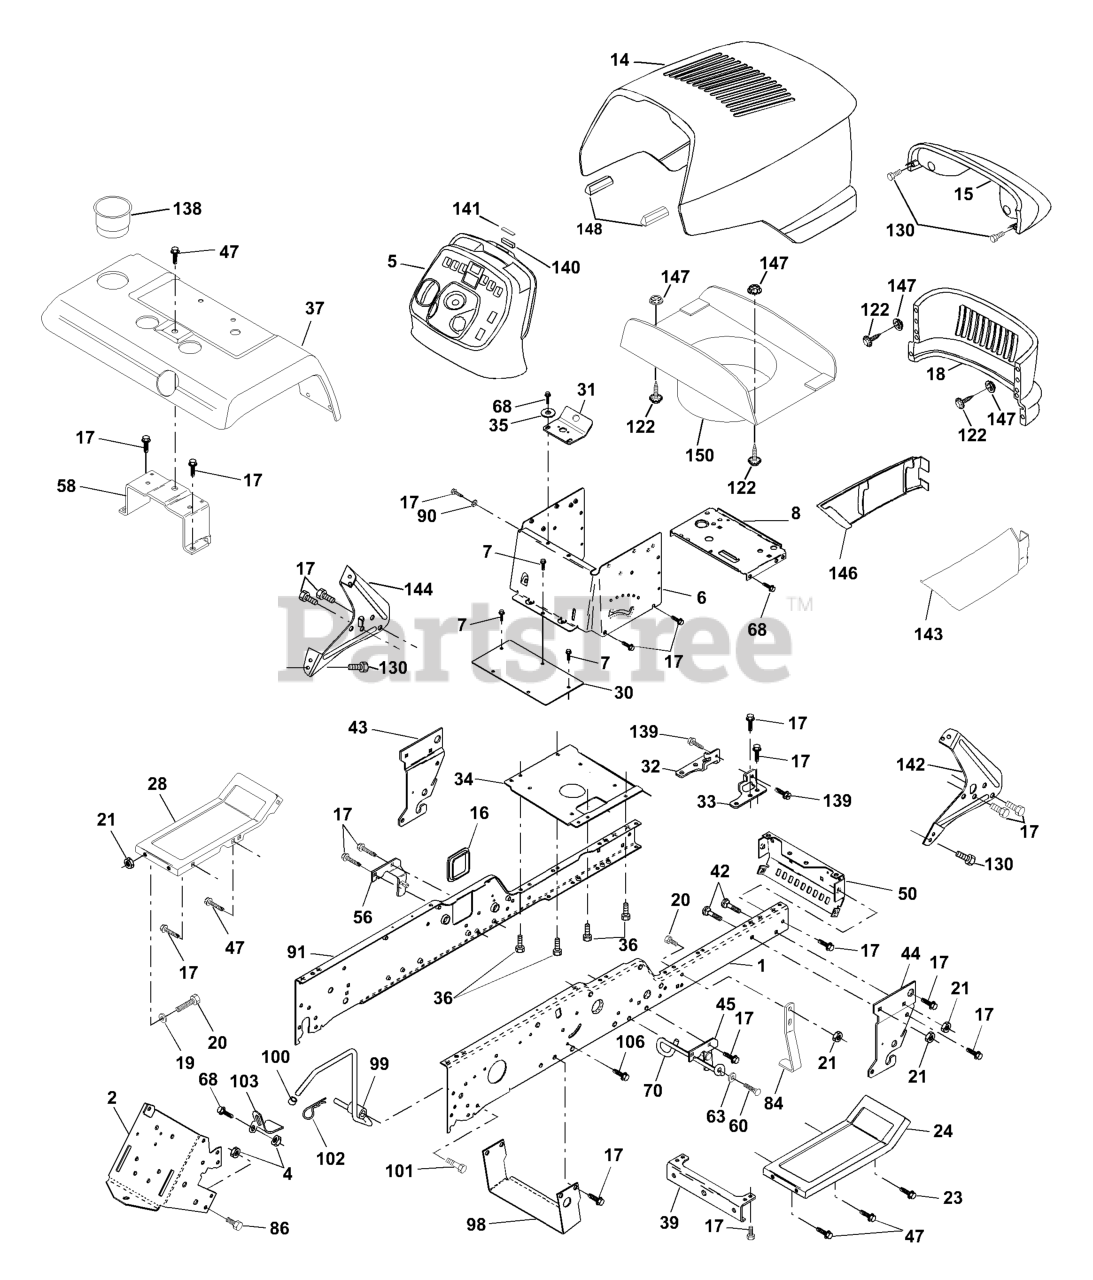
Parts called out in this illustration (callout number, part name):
1	RAIL, FRAME RH
2	DRAWBAR, GT
4	Nut, Lock Hex 7/16 Unc
5	DASH.STEALTH.YTGT.2CYL.BLK
6	DASH VGT, LOWER
7	SCREW
8	SUPPORT, BATTERY
14	HOOD ASM.
15	LENS, HEADLIGHT BAR
16	COVER ACCESS
17	SCREW 3/8-16X3/4
18	GRILLE
19	WASHER
20	BOLT
23	SCREW THDROL 3/8-16 X 1-1/2
24	FOOTREST RH
28	FOOT REST LH
30	SADDLE.HYDRO.95
31	BRACKET SUPT 1-PC VGT STEERING
34	PLATE ASM ENG CHASSIS
35	WASHER
36	SCREW 5/16"
37	FENDER
39	BRACKET AXLE, FRONT
42	BOLT D
43	FRONT SUSPENSION BRKT LH
44	FRONT SUSPENSION BRKT RH
45	BRACKET SUSP RH
47	SCREW 3/8-16X1/2
50	BRACKET, CHASSIS FRONT
56	BRACKET ASM, SUSP CHASSIS
58	BRACKET ASM, FENDER
60	SCREW.3/8-16
63	WASHER
68	Screw, 5/16-18 x 1/2
70	BELT GUIDE
84	MOWER STOP
86	BOLT
90	LOCKWASHER
91	RAIL, FRAME LH
98	BRACKET CHASSIS
99	ROD ASMBLY BYPASS
100	PLUNGER CAP
101	SCREW LT
102	RETAINER M
103	BRACKET LOCK BYPASS
106	SCREW
122	SCREW.HEX.WS.HD.8-18 X 7/8
130	SCREW
138	CUPHOLDER
139	BOLT, SHOULDER 5/16-18
140	MAGNET STEALTH
141	STRIKER PLATE
142	BRACKET DASH STEALTH(R)
143	SKIRT GRILLE RH
144	BRACKET DASH STEALTH LH
146	SKIRT GRILLE LH
147	SCREW
148	EXTRUSION BUMPER (3 2) (2 2)
150	DUCT HEAT HOOD
